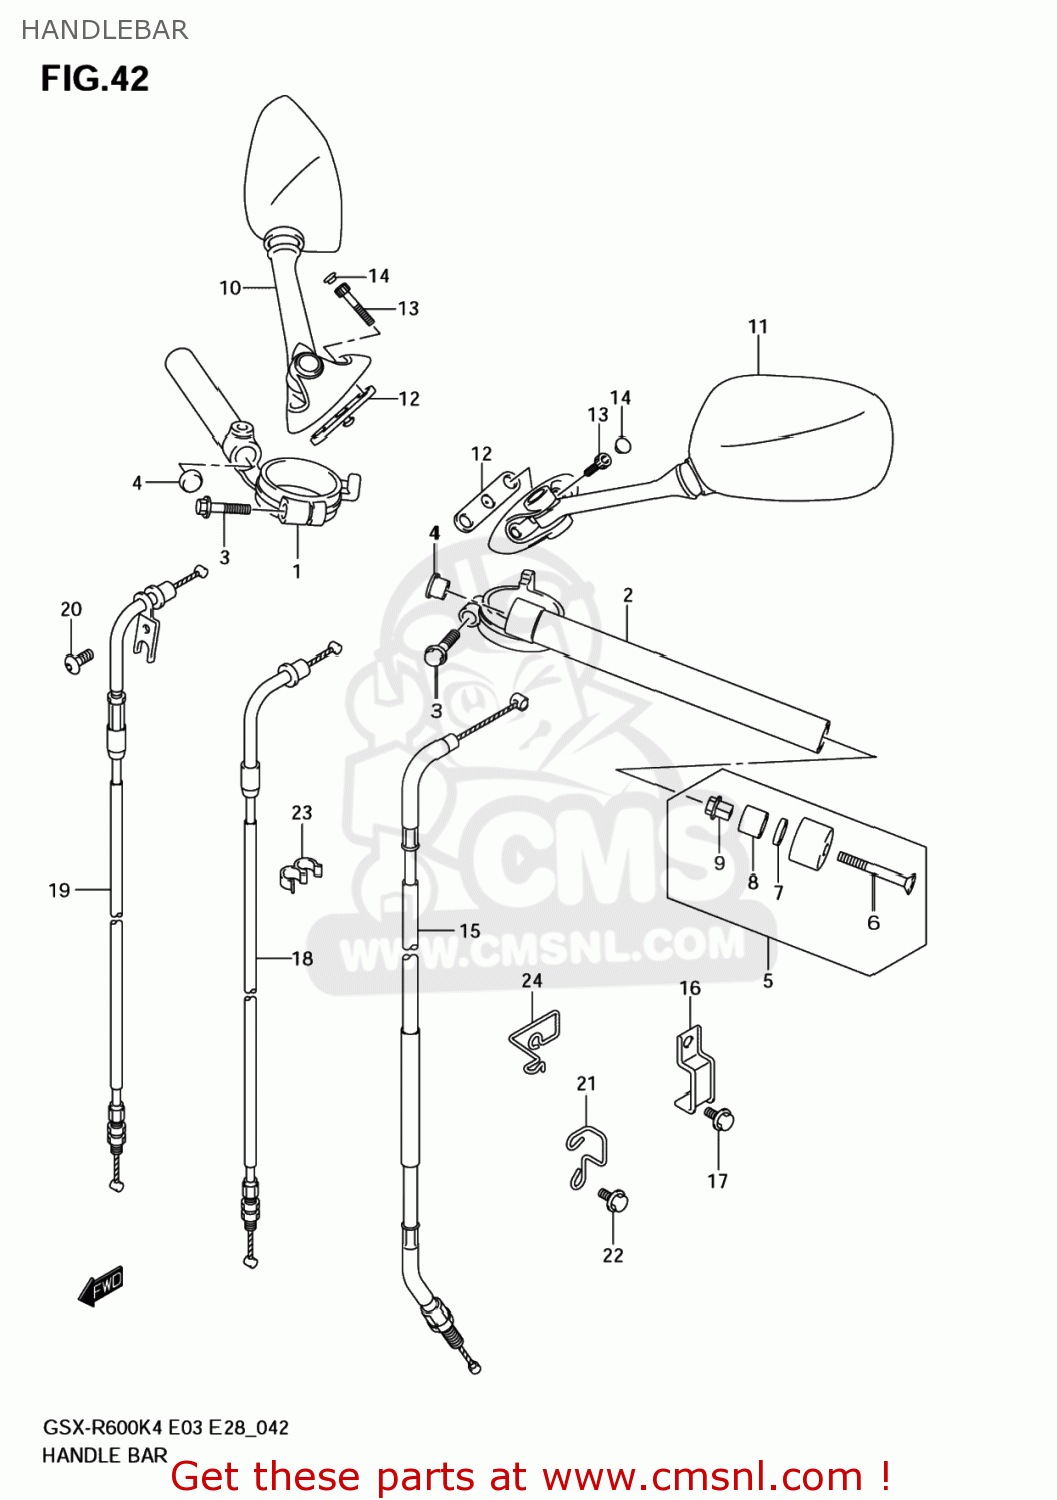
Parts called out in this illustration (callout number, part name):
1	HANDLEBAR,R
2	HANDLEBAR,L
3	BOLT,HANDLEBAR
4	CAP,HANDLEBAR
5	BALANCER SET
6	SCREW
7	WASHER(6.5X16X4)
8	EXPANDER,HANDLE BALANCER
9	NUT,HANDLE BAL
10	MIRROR ASSY,RR VIEW,R
11	MIRROR ASSY,RR VIEW,L
12	CUSHION,RR VIEW MIRRORR
13	BOLT
14	CAP(OD:10)
15	CABLE ASSY,CLUTCH
16	GUIDE,THROTTLE CABLE
17	BOLT
18	CABLE ASSY,THR
19	CABLE ASSY,THR
20	SCREW
21	GUIDE,THROTTLE CABLE
22	BOLT
23	CLAMP
24	GUIDE,THROTTLE
